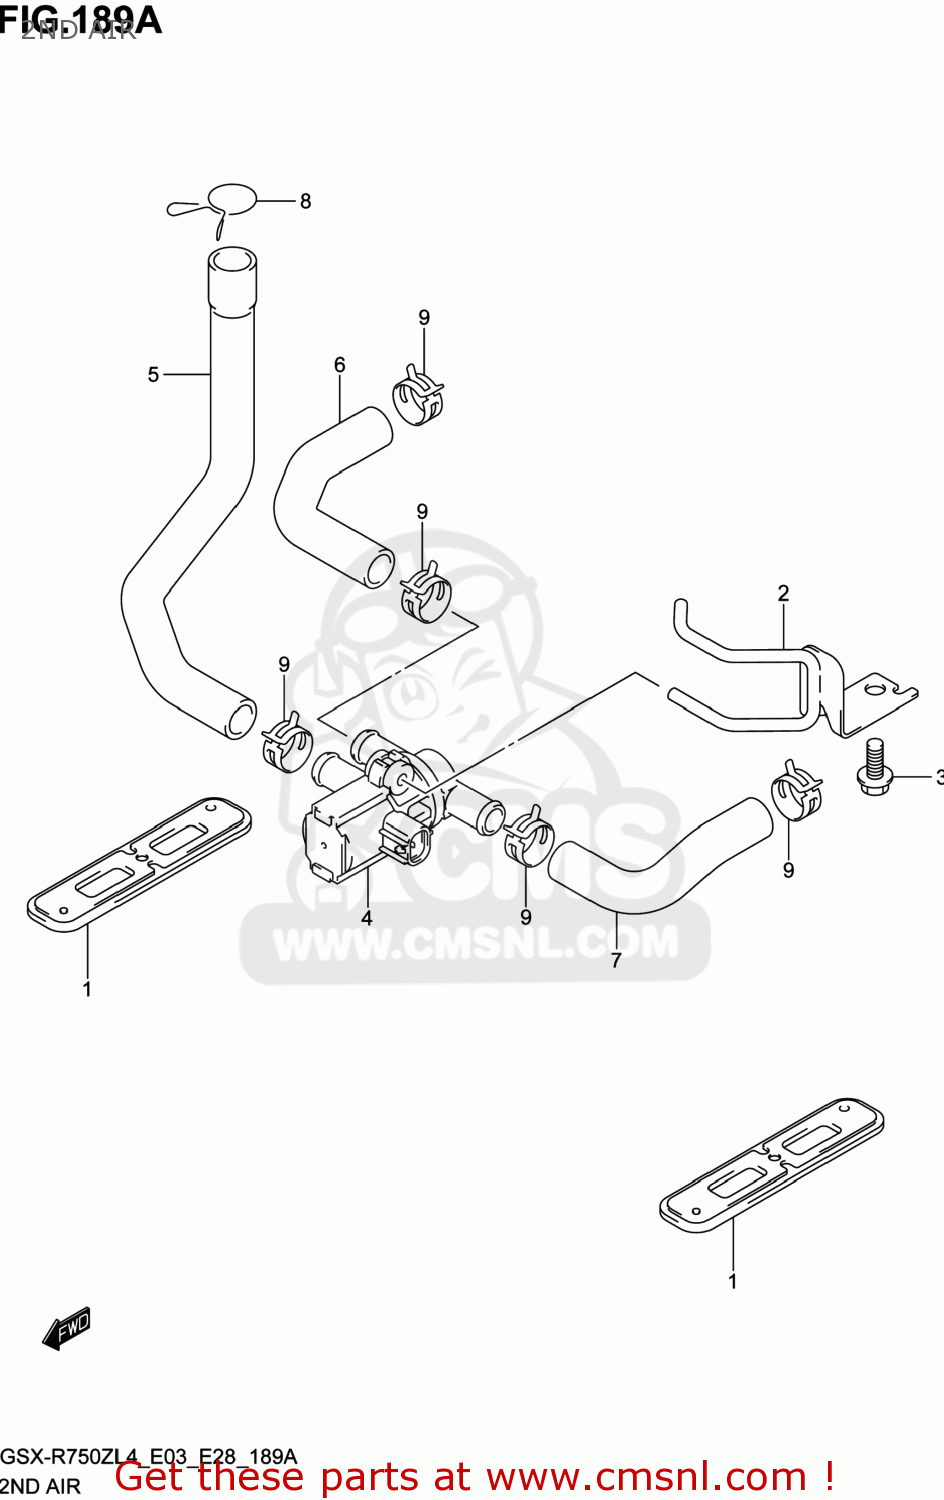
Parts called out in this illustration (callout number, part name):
1	VALVE ASSY,2ND AIR REED
2	BRACKET,2ND AIR VALVE
3	BOLT
4	VALVE ASSY,AIR CUT
5	HOSE,2ND AIR CLEANER
6	HOSE,2ND AIR VALVE,R
7	HOSE,2ND AIR VALVE,L
8	CLIP
9	CLIP
